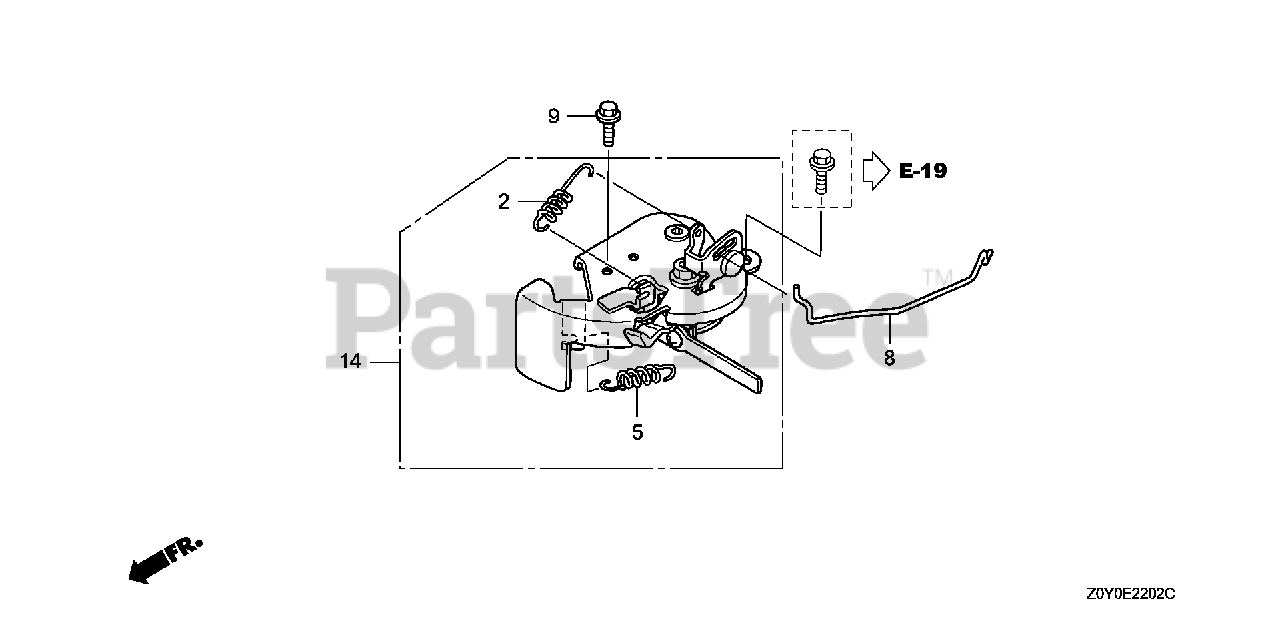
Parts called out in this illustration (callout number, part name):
2	SPRING, RETURN
5	SPRING, CHOKE LEVER
8	ROD, STOP
9	BOLT, FLANGE (6X20) (CT200)
14	LEVER ASSY., CHOKE
